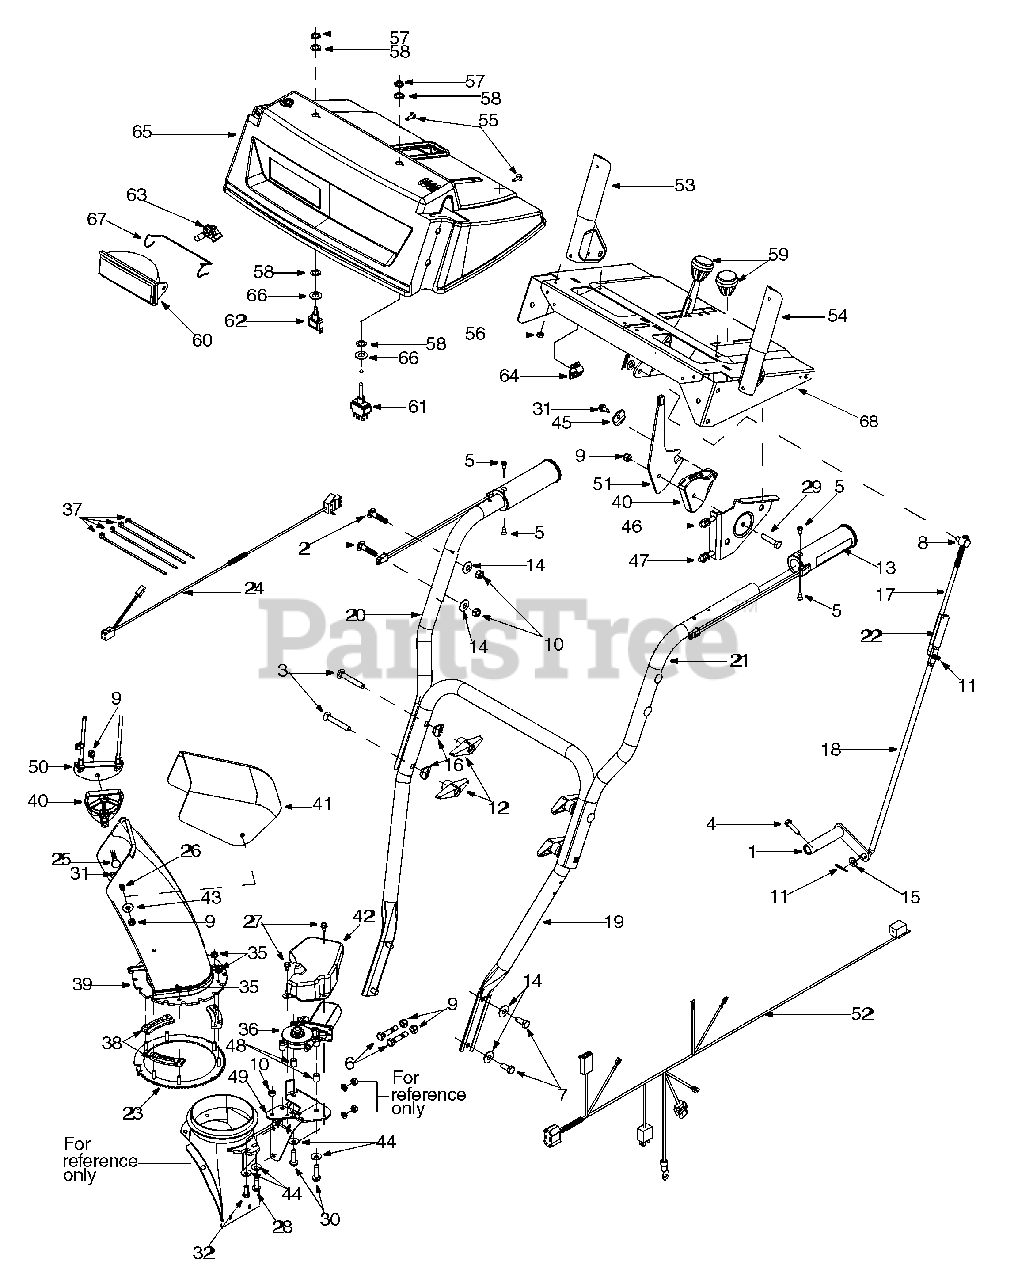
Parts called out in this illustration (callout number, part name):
2	Carriage Bolt 5/16-18 x 1.5"
3	Carriage Bolt 5/16-18 x 2.25"
4	TT Screw 1/4-20 x 1"
5	Oval C-Sk. Screw AB #10-16 x 0.625"
6	Shear Bolt 5/16-18 x 1.5"
7	Hex Screw 5/16-18 x .75"
8	Ferrule
9	Hex Lock Nut 5/16-18
10	Hex Nut 5/16-18
11	Cotter Pin
12	Handle Knob
13	Heated Grip
14	Belleville Washer
15	Flat Washer
16	Saddle Washer
17	Shift Rod: Upper
18	Shift Rod: Lower
23	Gear Assembly: Ring
24	Electric Harness: Lower
25	Carriage Bolt: 5/16-18 x 1.5"
26	Carriage Bolt: 5/16-18 x .75"
27	TT Screw: 1/4-20 x 0.5"
28	TT Screw: 5/16-18 x 1"
29	Hex Screw: 5/16-18 x 1.5"
30	TT Screw: 5/16-18 x 1.25"
31	Hex Screw AB: 1/4-14 x 0.625"
32	Hex Screw: 5/16-18 x .75"
35	Hex Flange Lock Nut
36	Electric Motor: Chute Crank
37	Cable Tie
38	Chute Flange Keeper
39	Lower Chute
40	Cable Guide: Chute Tilt
41	Upper Chute
42	Motor Cover: Chute Rotation
43	5/16 Washer
44	Belleville Washer
45	Special Washer
46	Control Cable
47	Control Cable
52	Harness Assembly: Upper
53	Handle Assembly RH: Engagement, Black
54	Handle Assembly LH: Engagement, Black
55	Special Hex Screw
56	Hex Sems Nut: 1/4-20
58	Lock Ring: Toggle Switch
59	Shift Knob
60	Lamp Housing
61	Toggle Switch: Double Throw
62	Toggle Switch: Single Throw
63	Halogen Lamp: 50W, 12V
64	Mounting Clamp
65	Handle Panel Cover
66	Flat Washer
67	Headlight Retainer
